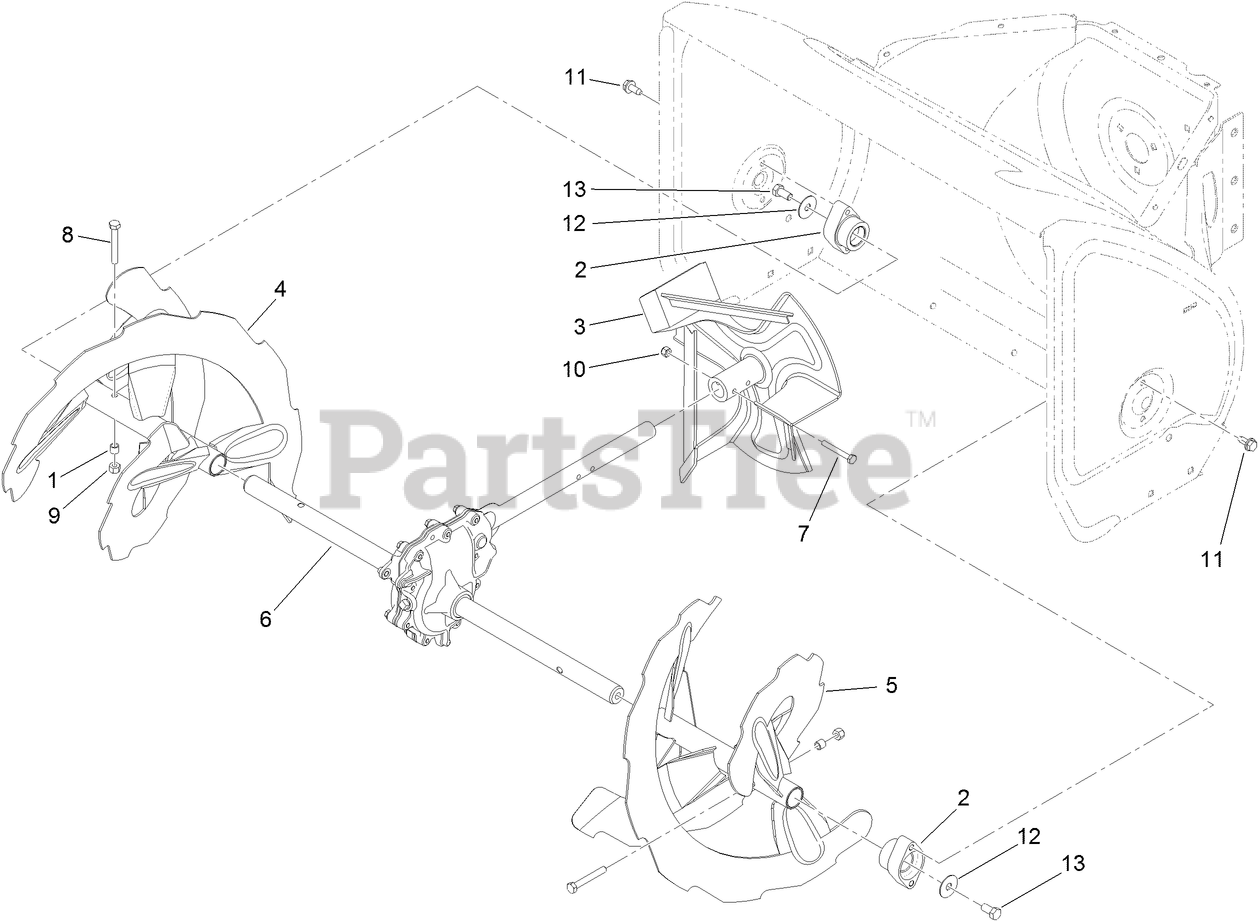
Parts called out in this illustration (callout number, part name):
1	SPACER
2	BEARING-AUGER
3	IMPELLER ASM
4	RH AUGER ASM
5	LH AUGER ASM
6	28 INCH AUGER GEARCASE ASM
7	SCREW-HH
8	SCREW-HH
9	NUT-LOCK, NI
10	NUT-LOCK, NI
11	SCREW-HWHTF
12	WASHER
13	SCREW-HH
